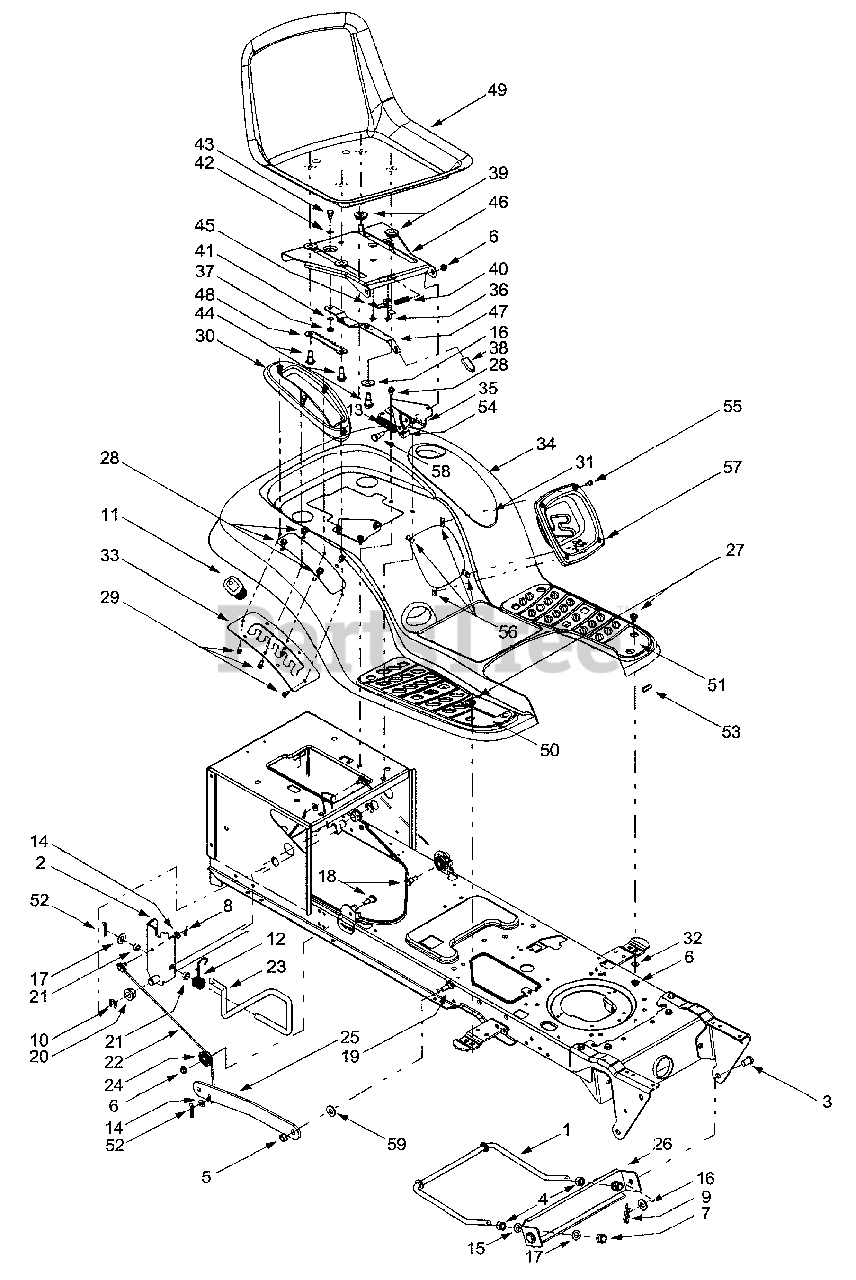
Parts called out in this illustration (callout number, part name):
1	Deck Stabilizer Rod
3	Clevis Pin, .5 x .78
4	Hex Nut, 1/2-13
5	Flange Lock Nut, 3/8-16
6	Flange Lock Nut, 5/16-18
7	Hex Nut, 1/2-13
8	Internal Cotter Pin
9	Internal Cotter Pin
11	Handle Grip
12	Torsion Spring
13	Extension Spring, .872 x 3.4
14	Flat Washer, 5/16
15	Lock Washer, 1/2
16	Flat Washer, .31 x 1.062 x .134
17	Flat Washer, .51 x 1.12 x .06
18	Hex Cap Screw, 5/16-18 x .62
19	Shoulder Screw, 3/8-16
20	Hex Flange Bearing
21	Snap Flange Bearing
22	Lift Cable, 16.16
23	Lift Handle
24	Roller Pulley
27	Carriage Bolt, 5/16 x .62
28	Self-tapping Screw, 5/16-18 x .625
29	Self-tapping Screw, 1/4-15 x .75
30	Lift Lever Cover
31	Cover w/ Cup Holder
32	Flat Washer, .349 x 1.0 x .063
36	Screw, #10-16 x .375
37	Hex Flange Lock Nut, 1/4-20
38	Seat Adjuster Grip
40	Compression Spring, .41 x 1.5
41	Spring Washer, .265 x .562 x .025
42	Flat Washer, .344 x .62 x .03
43	Shoulder Screw, .340 x .285, 1/4-20
44	Shoulder Screw, .50 x .50, 3/8-16
45	Seat Stop
48	Seat Adjustment Selector
49	Medium Back Seat, Black
50	RH Foot Pad
51	LH Foot Pad
52	Cotter Pin
53	Trim Strip
54	LH Seat Lift Bracket
55	Phillips Pan Screw, 1/4-20 x .75
56	U-type Speed Nut, 1/4-20
57	Shift Lever Cover
58	Shoulder Screw, .437 x .286
59	Flat Washer, .53 x .93 x .05
